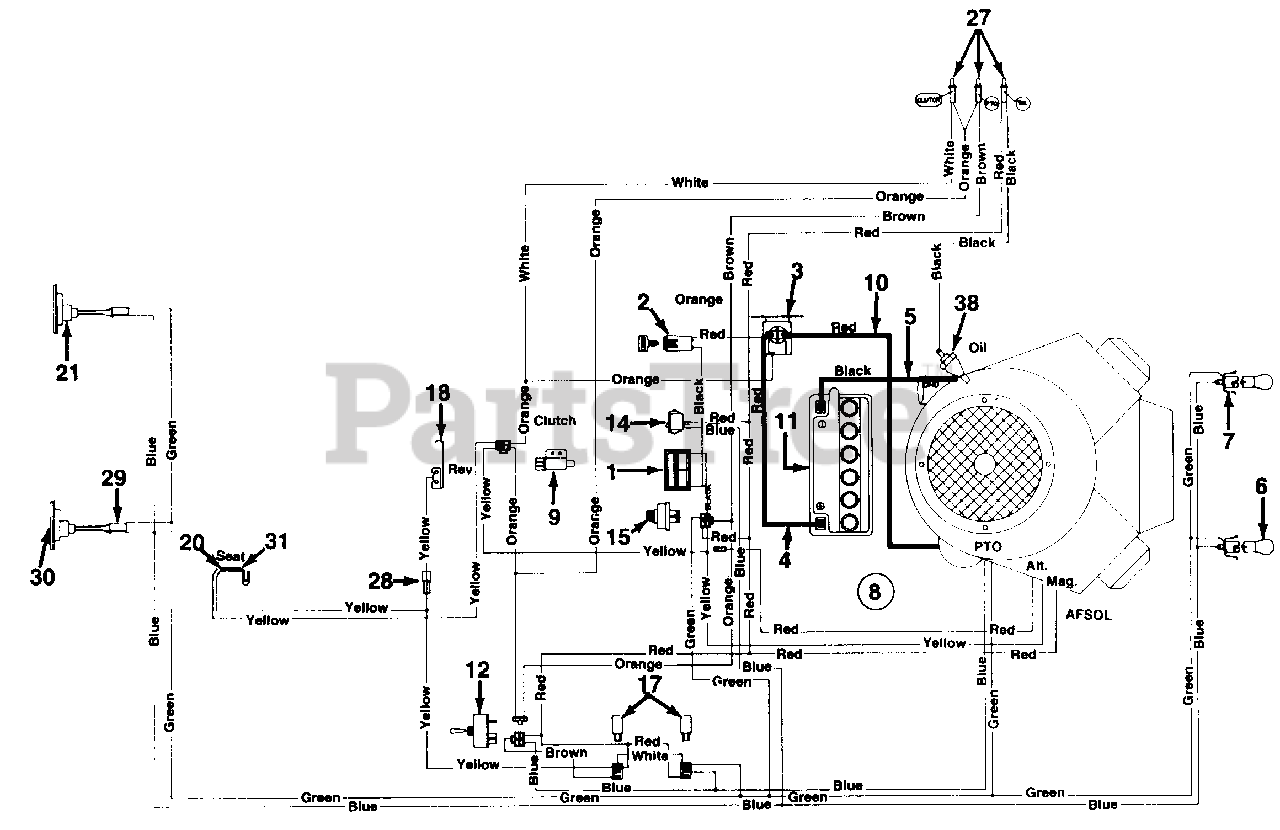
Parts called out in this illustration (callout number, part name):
1	Ammeter
2	Fuse 20 Amp
3	Solenoid
4	Wire
5	6 Ga. Red Wire 20" Lg.
6	Bulb
7	Socket
8	Wire Harness
9	Safety Switch (Clutch)
10	6 Ga. Black Wire
11	Battery (275 Cold Crank Amps)
12	Switch (PTO)
14	Light Switch
15	Ignition Switch
17	Relay
18	Spring Lever
20	Safety Switch (Seat)
21	Taillight
27	Bulb
28	Transmission Ext. Wire
29	Taillight Harness
30	Bulb
31	Safety Switch (Seat)
38	Oil Pressure Switch
